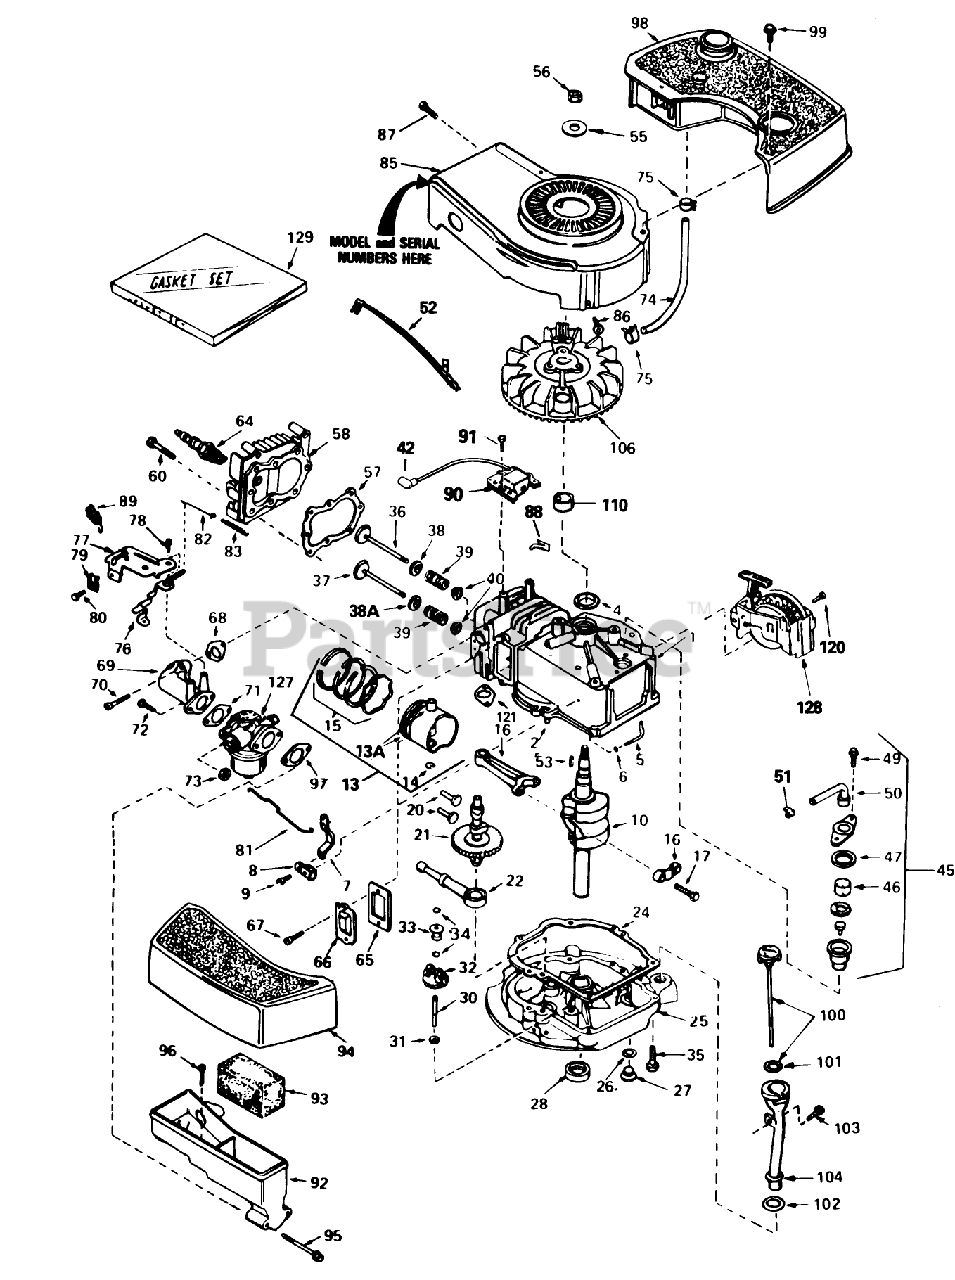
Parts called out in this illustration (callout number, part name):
1	Cylinder Assy. (Inc. #2 4)
2	Pin-Dowel
4	Seal-Oil
5	Rod, Governor (Incl. No. 36)
6	Washer-Flat
7	Governor Lever
8	Clamp-Lever, Governor
9	Screw
10	Crankshaft
13	Piston, Pin Ring Assy. (Std.) (Incl. Ref. #13A, 14 15)
13	Piston, Pin Ring Assy. (.010 oversize) (Incl. Ref. #13A, 14 15)
13	Piston, Pin Ring Assy. (.020 oversize) (Incl. Ref. #13A, 14 15)
13A	Piston Pin Assy. (Incl . Ref. . #14) (Std.)
13A	Piston Pin Assy. (Incl. Ref. #14) (.010 Oversize)
13A	Piston Pin Assy. (.020 oversize) (Incl. Ref. #14)
14	Ring-Retaining, Piston Pin
15	Ring Set (Std.)
15	Ring Set (.020" OS)
15	Ring Set (.010" OS)
16	Rod Assy., Connecting (Incl. Ref. #17)
17	Bolt-Rod, Connecting
20	Lifter-Valve
21	Camshaft(Mech.Comp. Release)
22	Oil Pump ASM
24	Gasket
25	Flange Assy.-Mounting (Incl. Ref. #26, 27, 28 31)
26	Gasket-Oil Drain
27	Plug Oil Drain
28	Seal Oil
30	Shaft-Governor
31	Washer-Flat
32	Governor Gear ASM
33	Spool-Governor
34	Ring-Retaining
35	Screw (1/4-20 x 1-1/4)
36	Valve, Intake (Std.) (Incl. Ref. #40)
36	Valve, Intake (1/32" oversize)(Incl. No. 40)
37	Valve, Exhaust (Std.)(Incl. No. 40)
37	Valve, Intake (1/32" oversize)(Incl. No. 40)
38	Seal Assy., Intake
38A	Cap-Upper Valve Spring
39	Spring-Valve
40	Cap-Valve, Spring
42	Cover-Spark Plug
45	Breather Assy. (Incl. Ref. #46 thru 51)
46	Element-Breather
47	Gasket-Breather
49	Screw (10-24 x 9/16)
50	Tube, Breaker
51	Clip, Breather
52	Wire-Ground
53	Key-Flywheel
55	Washer-Belleville
56	Nut-Flywheel
57	63573 GIL 42 SNWTHW
58	Head-Cylinder
60	Screw (5/16-18x1-1/2)
64	Spark Plug-Resistor (R J19 L M)
65	Gasket-Breather
66	Cover-Valve
67	Screw
68	Gasket-Intake
69	Pipe, Intake (Incl. No. 68)
70	Screw (1/4-20 x 1)
71	Gasket-Carburetor
73	Nut and Lock Washer (1/4-28)
74	Line-Fuel
75	Clamp-Line, Fuel
76	Lever Control
77	Control Assy., Speed (Incl. Nos, 76, 78 89)
78	Screw, Hex Washer Hd Shoulder Self-Tap
79	Conduit
80	Screw (10-32 x 3/8)
81	Link-Throttle
82	Link Governor Spring
83	Spring Governor
85	Housing-Blower
86	Screw (1/4-20x19/32)
87	Screw (10-24 x 9/16)
88	Clip-Wire
89	Terminal
90	Solid State
91	Screw
92	Body Air Cleaner
93	Filer, Air
94	Cove, Air Cleaner
95	Screw Fil Hd.
96	Screw, Hex Washer Hd Shoulder Self-Tap
97	Gasket-Air Cleaner
98	Tank-Fuel
99	Screw (10-32 x 35/64)
100	Dipstick, Oil (Incl. Ref. #101)(Twist Lock)
101	O-Ring
102	Gasket
103	Screw (10-32 x 1/2)
104	Tube-Oil Fill
106	Flywheel
110	Spacer
120	Screw (1/2-20x5/8)
121	Gasket Exhaust
127	Carburetor (Incl. Ref. #71)
128	Starter-Sidemount
129	Gasket Set
